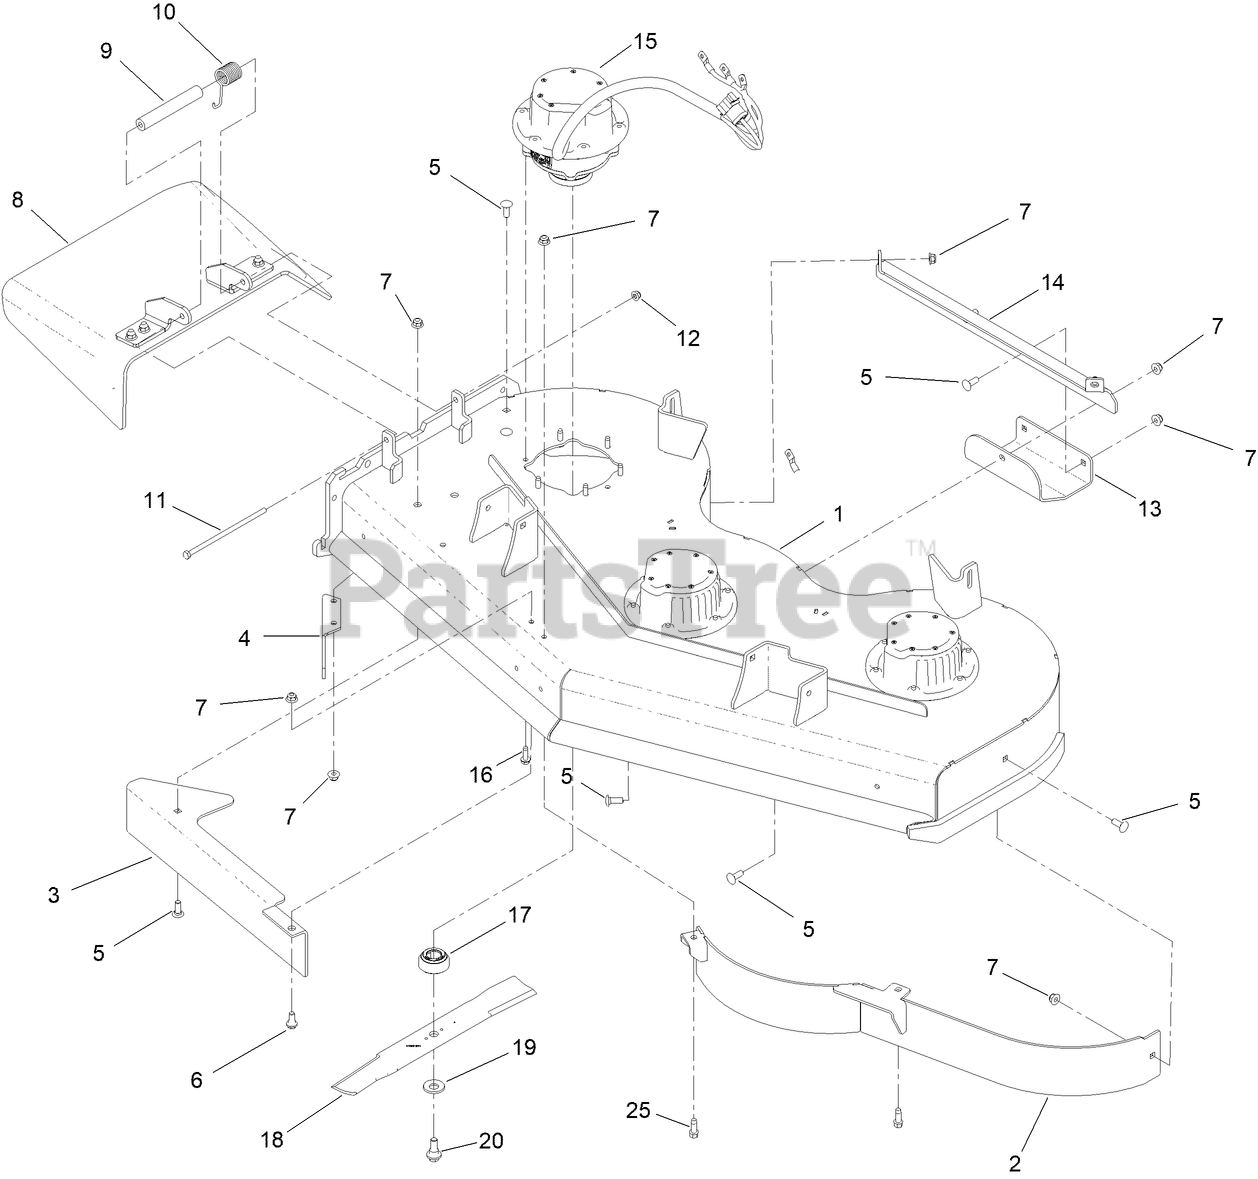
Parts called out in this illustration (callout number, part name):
1	DECK ASM, 52IN
2	BAFFLE ASM, FRONT
3	PLATE-BAFFLE, FORMED [RED]
4	BAFFLE-DISCHARGE
5	SCREW-CARR
6	BOLT-SHOULDER
7	NUT-HF, NI
8	RUBBER DEFLECTOR ASM
9	SPACER
10	SPRING-TORSION
11	SCREW-HH
12	NUT-HF, NI
14	BRACKET-SKID
15	MOTOR/GEN-48V,
16	SCREW-THD ROLL, HWH
17	RETAINER-BLADE
18	BLADE-18.0IN, MED SAIL
19	WASHER-BELLEVILLE
20	SCREW-SHOULDER,HWH
